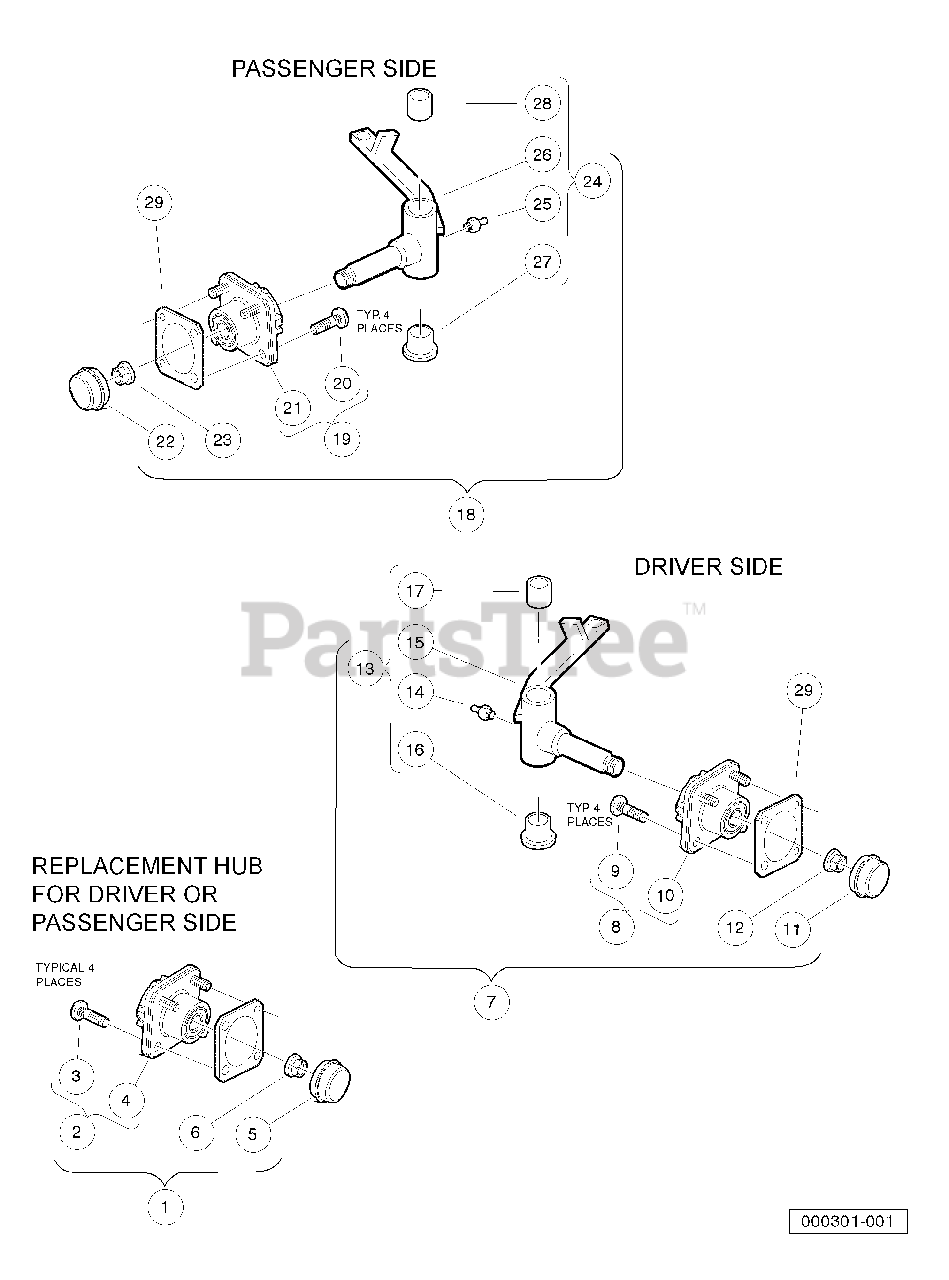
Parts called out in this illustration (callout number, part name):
1	Replacement Kit, Front Hub
2	Front Hub Assembly, Ball Bearing
3	Lug Stud, 1/2-20 UNF, 4037 Stl
4	Hub, Front
5	Cap, Front Hub
6	Hex Nut, Locking Flange, M14x2
7	Asm, Front Hub And Spindle, Left-Hand
9	Lug Stud, 1/2-20 UNF, 4037 Stl
10	Hub, Front
11	Cap, Front Hub
12	Hex Nut, Locking Flange, M14x2
13	Assembly, Spindle, Left-Hand
14	Fitting, 1/4-28 Thread-Forming Grease
15	Sub-Assembly, Spindle, Left-Hand
16	Bushing, Flanged Bronze
17	Bushing, Bronze Spindle
18	Asm, Front Hub And Spindle, Right-Hand
19	Front Hub Assembly, Ball Bearing
20	Lug Stud, 1/2-20 UNF, 4037 Stl
21	Hub, Front
22	Cap, Front Hub
23	Hex Nut, Locking Flange, M14x2
24	Assembly, Spindle, Right-Hand
25	Fitting, 1/4-28 Thread-Forming Grease
26	Sub-Assembly, Spindle, Right-Hand
27	Bushing, Flanged Bronze
28	Bushing, Bronze Spindle
29	Spacer Wheel
